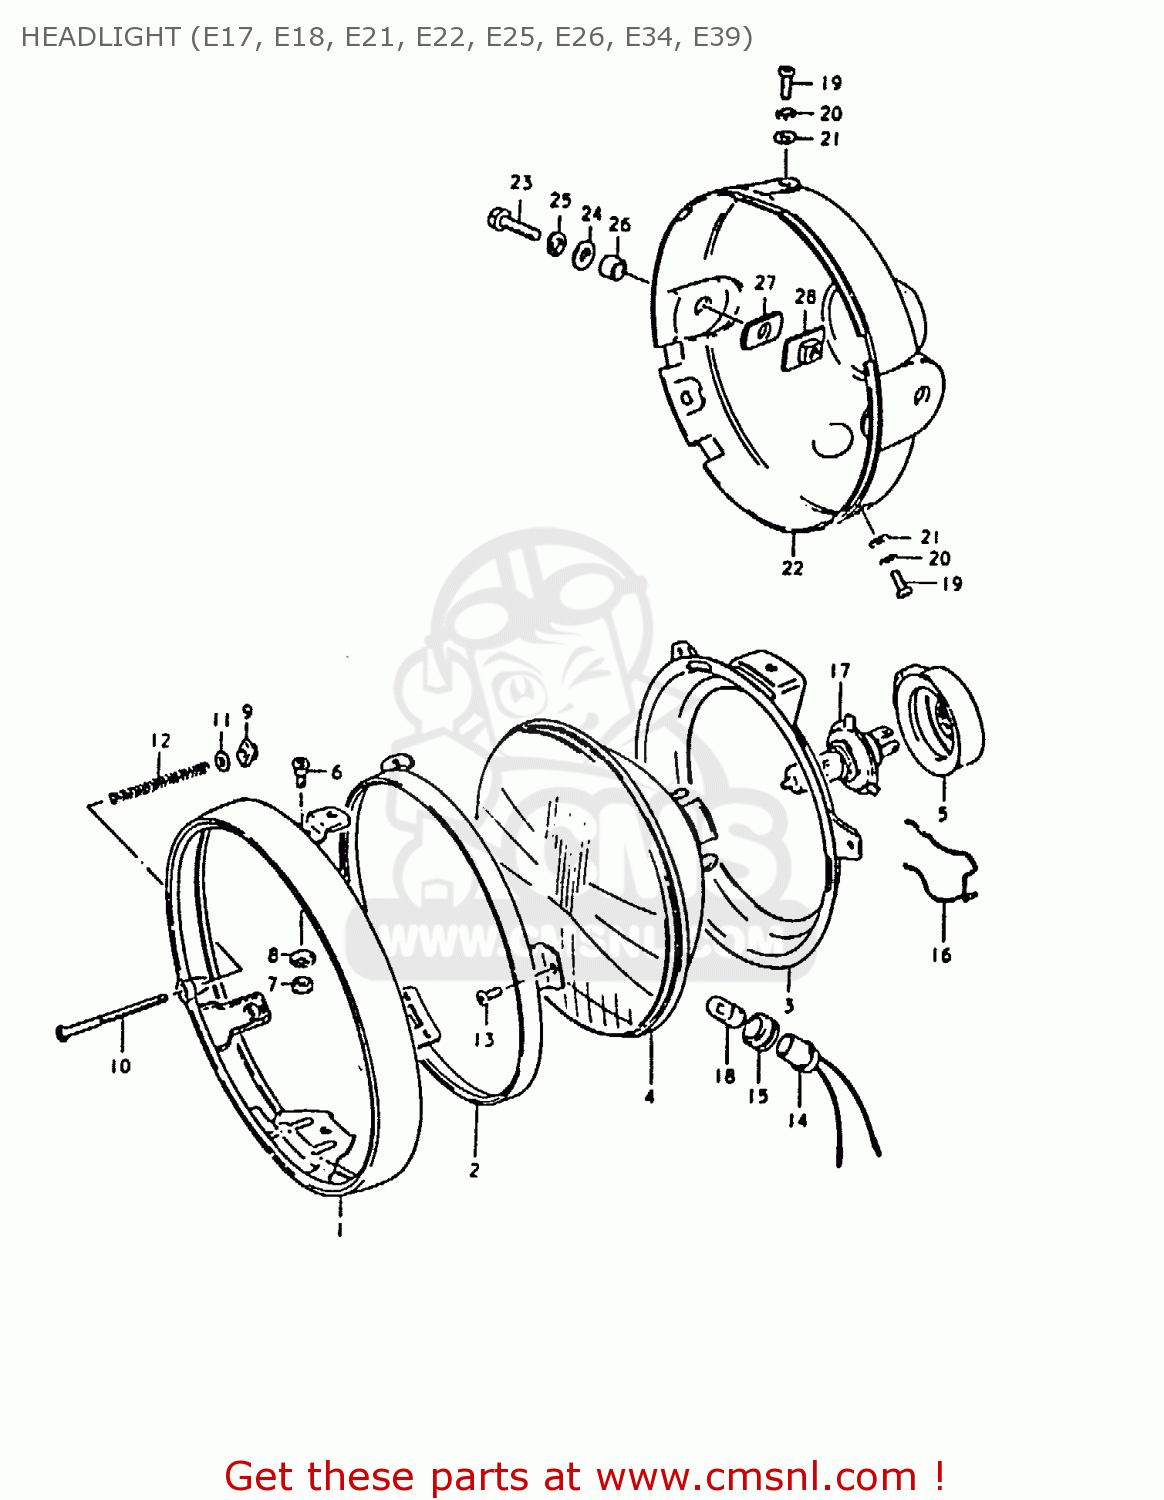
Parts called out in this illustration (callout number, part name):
1	RIM
2	RETAINER
3	RING,HEADLAMP UNIT
4	UNIT,HEAD LAMP
5	COVER,HEADLAMP SOCKET
6	SCREW
7	NUT,ADJUSTING
8	SPACER
9	NUT
10	SCREW,HEADLAMP ADJUST
11	WASHER
12	SPRING,HEADLAMP ADJUST
13	SCREW
14	SOCKET
15	JOINT,RUBBER
16	CLAMP,HEADLAMP SOCKET
17	BULB(12V60/55W,H4)
18	BULB(12V4W)
19	SCREW
20	WASHER,LOCK
21	WASHER
22	HOUSING,HEADLAMP(BLACK)
23	BOLT
24	WASHER
25	LOCK WASHER
26	SPACER (8.8X12X7)
27	CUSHION
28	PLATE,HEADLAMP HOUSING
